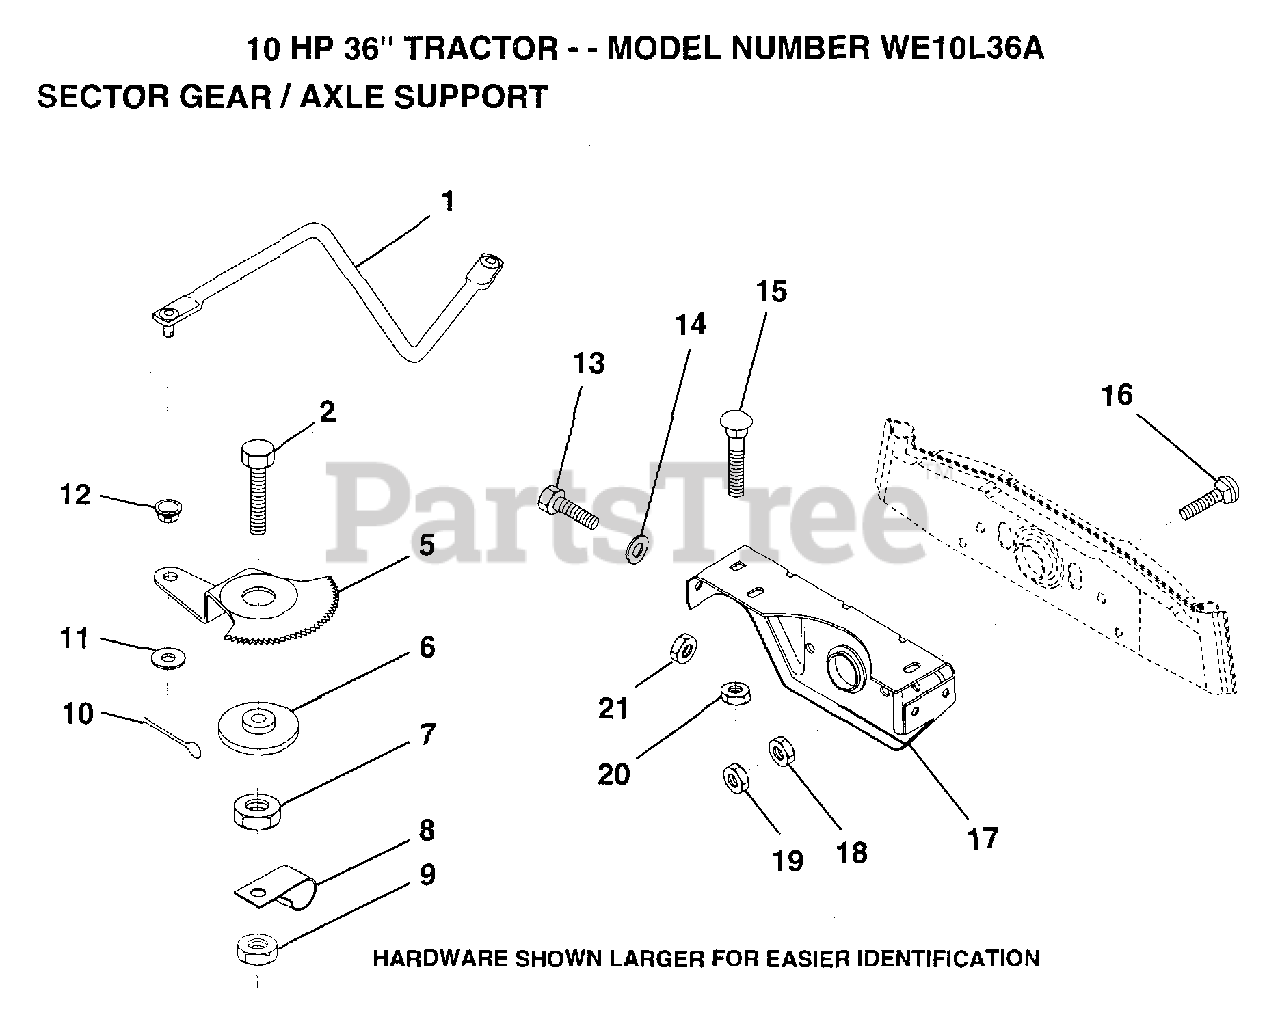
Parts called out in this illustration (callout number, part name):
1	DRAG LINK
2	"BOLT,HEX"
5	GEAR SECTOR
6	BUSHING
7	NUT
8	CLIP INSULATOR
9	NUT LTV
10	COTTER PIN
11	WASHER
12	BUSHING.DRAGLINK
13	BOLT
14	WASHER
15	BOLT
16	BOLT
17	"SUPT,FRT AXLE"
18	NUT.HEX.3/8-16UNC
19	LOCKNUT
